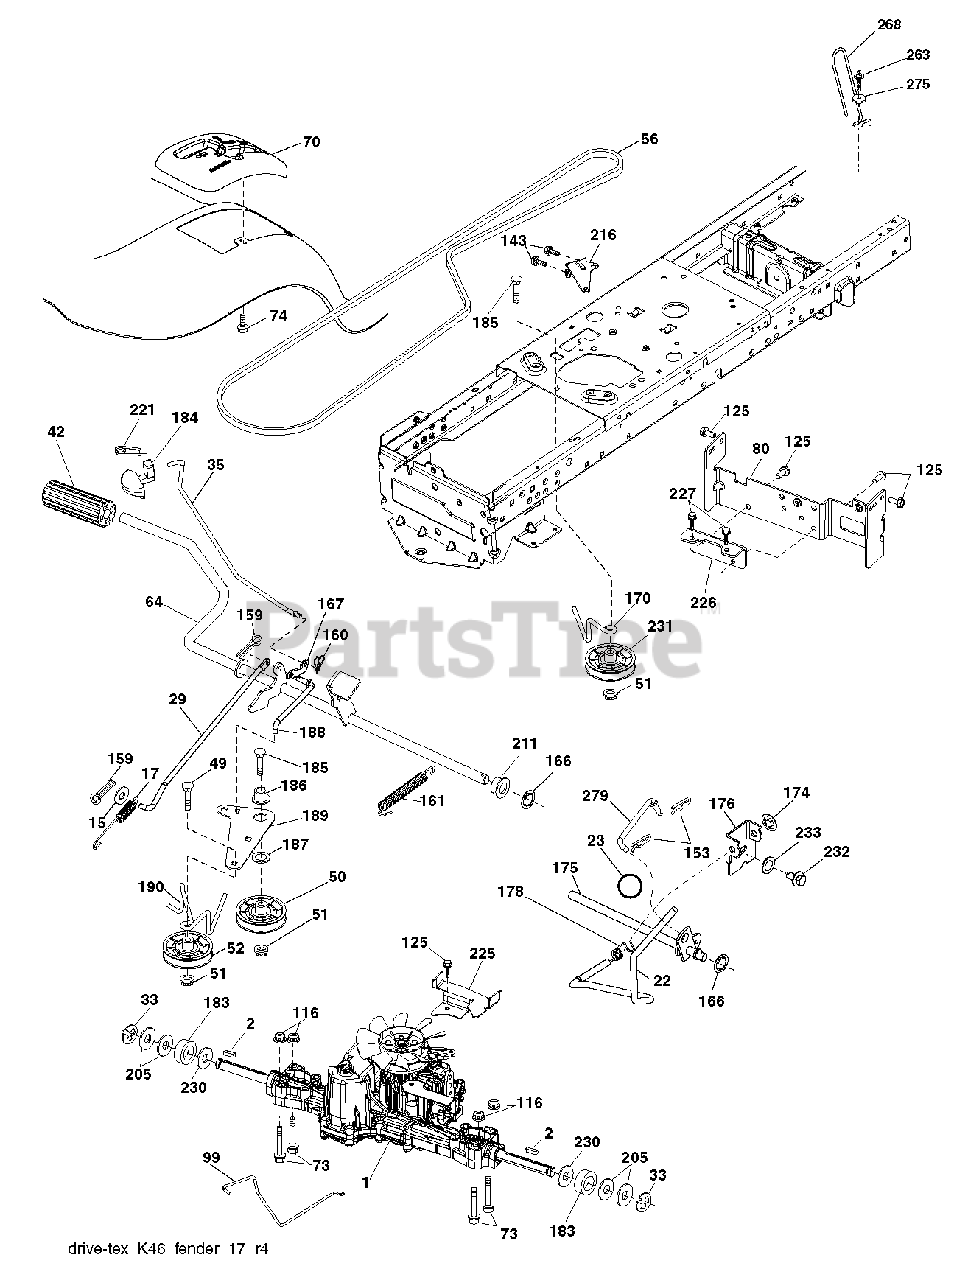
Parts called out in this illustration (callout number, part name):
2	SQUARE KEY
17	SPRING.BRAKE.K46.GREEN
22	ROD.SHIFT.FENDER.TLT.2006
23	KNOB.DUCKHEAD.1/2
29	ROD.BRAKE.K46
33	E-RING LT
35	ROD, BRAKE, PARK
42	PEDAL COVER T
49	BOLT
50	IDLER.FLAT.910.OFFSET
51	NUT LOCK FLG 3/8-16 UNC
52	IDLER.V-GROOVE.910.OFFSET
64	SHAFT.ASM.PEDAL.BRAKE.
70	CONSOLE.SHIFT.STL.HYD.BLACK
73	BOLT HEX 5/16-18 GR 5
74	SCREW.HI-LO.CONSOLE
80	STRAP TORQUE
99	ROD.SPRING.BYPASS.K46.LT.Z
116	NUT LOCK HEX FLANGE 5/16-18
125	SCREW
143	SCREW LT
153	RETAINER M
159	COTTER PIN
160	RETAINER CLIP
161	SPRING, RETURN LT
166	NUT.PUSH.625
167	LATCH.BRAKE.SPRING
170	KEEPER.CENTER SPAN.1.688
174	NUT.PUSH.500.2006
175	SHAFT.ASM.SHFT.T2.TLT
176	ARM.CLEVIS.ROD.SHIFT
178	SPRING.SHIFT.GT2006
183	SPACER AXLE
184	HANDLE PARKING BRAKE
186	SPACER.RETAINER
187	WASHER 12/32X2X10GA
188	LINK.CLUTCH.GROUND.DRIVE
189	BELLCRANK.GROUND.DRIVE.TEX.
190	KEEPER.BELLCRANK.DRIVE
211	BUSHING.SHAFT.BRAKE.HAND
216	BRACKET.PULLEY.IDLER.W/TEX
221	RETAINER.SPRING.CLIP.H
225	KEEPER.BELT.TRANSAXLE.K46
226	BRACKET.MOUNT.TORQUE.K46.TLT
227	SCREW
230	WASHER.HARDENED
231	IDLER.V-GROOVE.1.688.OFFSET
232	BOLT FIN HEX 7/16-14 X 1
233	WASHER SERRATED
263	SCREW, 3/8-16X3/4
275	WASHER
279	LINK.SHIFT.
